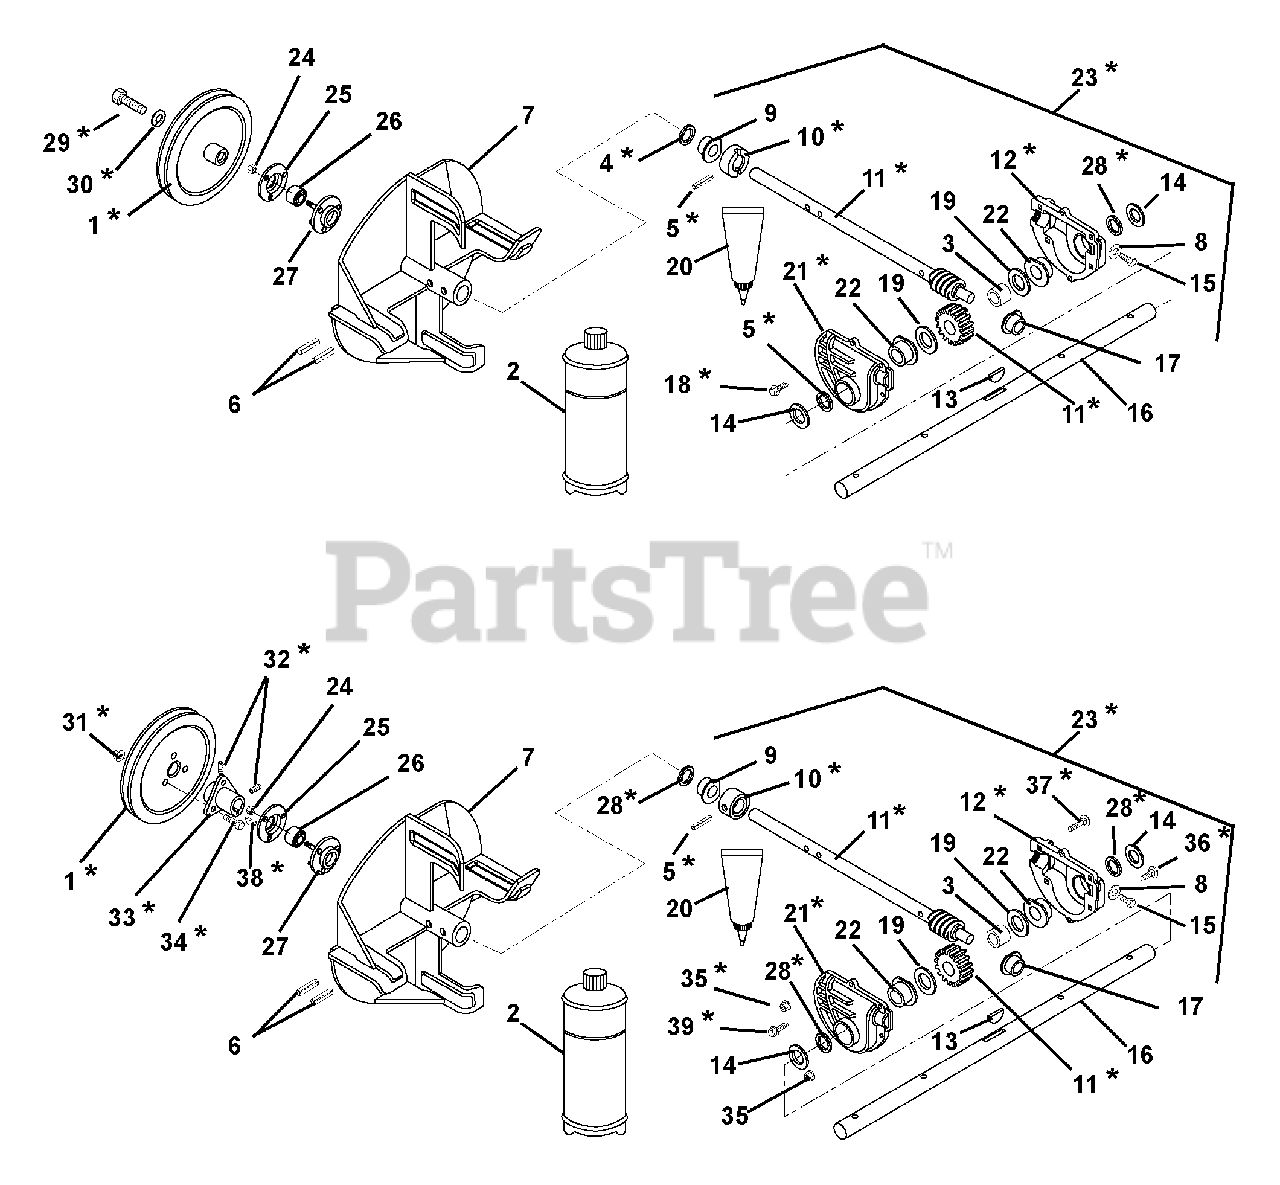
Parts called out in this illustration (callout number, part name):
1	PULLEY, 4L W/HUB, .75 X 8.5
1	PLY-V 8.50 X 1.25 3BLT
2	ARIENS 16 OZ.BOTTLE OF L2 LUBE
3	BSHG-SLV .755X1.500X.442
4	SEAL-OIL.748X1.378X.276 RBR OD
5	@PIN-GRV .188X1.25 TP E ALLOY
5	PIN-GRV .188X1.25 TP A
6	PIN-ROLL .250X1.25
7	IMPELLER - 10"
8	WSHR-FIBER .437X.656X.032
9	BSHG-FLG .750X1.000X.750X1.250
10	THRUST COLLAR, .75" ID
10	THRUST COLLAR
11	SHAFT AND WORM GEAR ASSEMBLY
12	GEARCASE CASTING, MACHINED LH
12	CASE, GEAR-LH-LARGE BORE-ALUM.
13	KEY-WDRF .188X.625X.25 SAE 61
14	@WSHR-FL-STL.812X1.50X.135YWZC
15	SCR-TAP .38-16X.75 ROLOK YZ WX
16	SHAFT, RAKE - 24" (.750 DIA)
16	SHAFT, RAKE - 20" (.750 DIA)
17	BSHG-FLG .502X1X.750
18	@SCR-TAP .25-20X1.00 HWH TR YZ
19	WSHR-HDND-THRST .755X1.40X.062
20	LOCTITE 518 GASKET--6ML TUBE
21	GEARCASE CASTING, MACHINED RH
21	CASE, GEAR-RH-LARGE BORE-ALUM.
22	BSHG-FLG .753X1.127X.500X1.501
23	GEARCASE, 24" ALUM, SMALL CD
23	GEARCASE, 20" ALUM, SMALL CD
23	GEAR CASE - ALUMINUM - 24"
23	GEAR CASE - ALUMINUM - 20"
24	@NUT-LK-CTR .25-20 YWZC
25	BEARING FLANGE
26	BRG-BALL .750X1.750X.50
27	BEARING FLANGE
28	SEAL-OIL .750X1.375X.250
29	BLT-HEX .31-24X1.0 GR5 YZ EP80
30	WSHR-LK .312X.097 HVY YWZC
31	@NUT-SPNLK-FLG .312-18 YWZC
32	SCR-SET .31-18X.38 SKHCUPDL
33	HUB ASSEMBLY
34	BLT-SERRDHD SL .31-18X.75 YZ
35	@NUT-SPNLK-FLG .25-20 YWZC
36	@BLT-RDHDSQNK .25-20X1.00 G5YZ
37	@BLT-RDHDSQNK .25-20X1.25 G5YZ
38	KEY-WDRF .188X.875X.375 SAE11
39	SCR-TAP 10-24X.75 HWH TR YWZC
